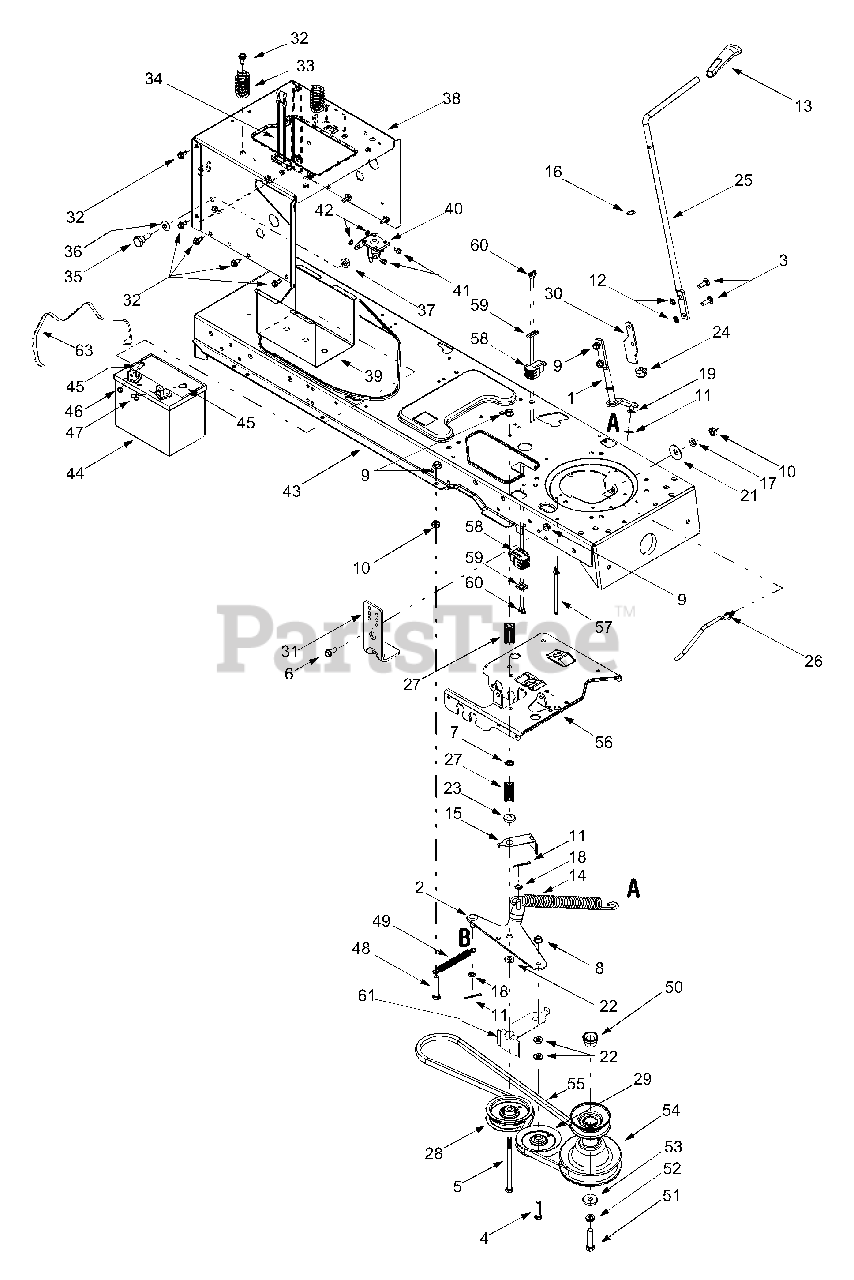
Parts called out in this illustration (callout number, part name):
1	PTO Engage Lever Assembly
4	Hex Cap Screw, 3/8-16 x 1.5
5	Hex Cap Screw, 3/8-16 x 5.5
6	AB Screw 5/16-12 x 0.75
7	Push Nut, 3/8
8	Lock Nut, 3/8-16
9	Flange Lock Nut, 5/16-18
10	Hex Nut, 5/16-18
11	Cotter Pin, 1/8 x 1.25
12	Speed Nut, .3125
13	PTO Knob
14	Extension Spring, .75 x 6.75
16	Flat Washer, .510 x .750 x .033
17	Lock Washer, 5/16
18	Flat Washer, .385 x .62 x .063
19	Flat Washer, 5/16
20	Flat Washer, .406 x .875 x .059
23	Shoulder Spacer, .380
24	Hex Split Flange Bearing, .5
26	Belt Keeper Rod
27	Spacer, 3/8 x 1.54
28	Idler Pulley, 3.5
29	Idler Pulley, 4.0
32	Self Tapping Screw, 5/16-18 x .625
33	Compression Spring, 1.28 x 3.125
34	Battery Strap
35	Shoulder Screw, .625 x .5, 7/16-20
36	Bell Washer, .45 x 1.0 x .062
37	Flange Lock Nut, 7/16-20
41	Self Tapping Screw, 1/4-20 x .5
42	Lock Washer, 1/4
44	12-volt Battery, 270 CCA
45	Hex Cap Screw, 1/4-20 x .62
46	Hex Sems Nut, 1/4-20
47	Wing Nut, 1/4-20
48	Extension Spring, .50 x 5.0
49	Hex Cap Screw, 5/16-18 x 1.75
50	Spacer Cup
51	Hex Head Cap Screw, 7/16-20 x 1.25
52	Lock Washer, 7/16
53	Flat Washer, .450 x 1.25
54	Engine Pulley, 3.56 OD x 5.56
55	PTO Belt
57	Keeper Pin, 5/16 x 4.75
58	Switch
59	Switch Plate
60	Screw, #10-16 x .5
61	Belt Guard
63	Battery Hold-Down Rod
